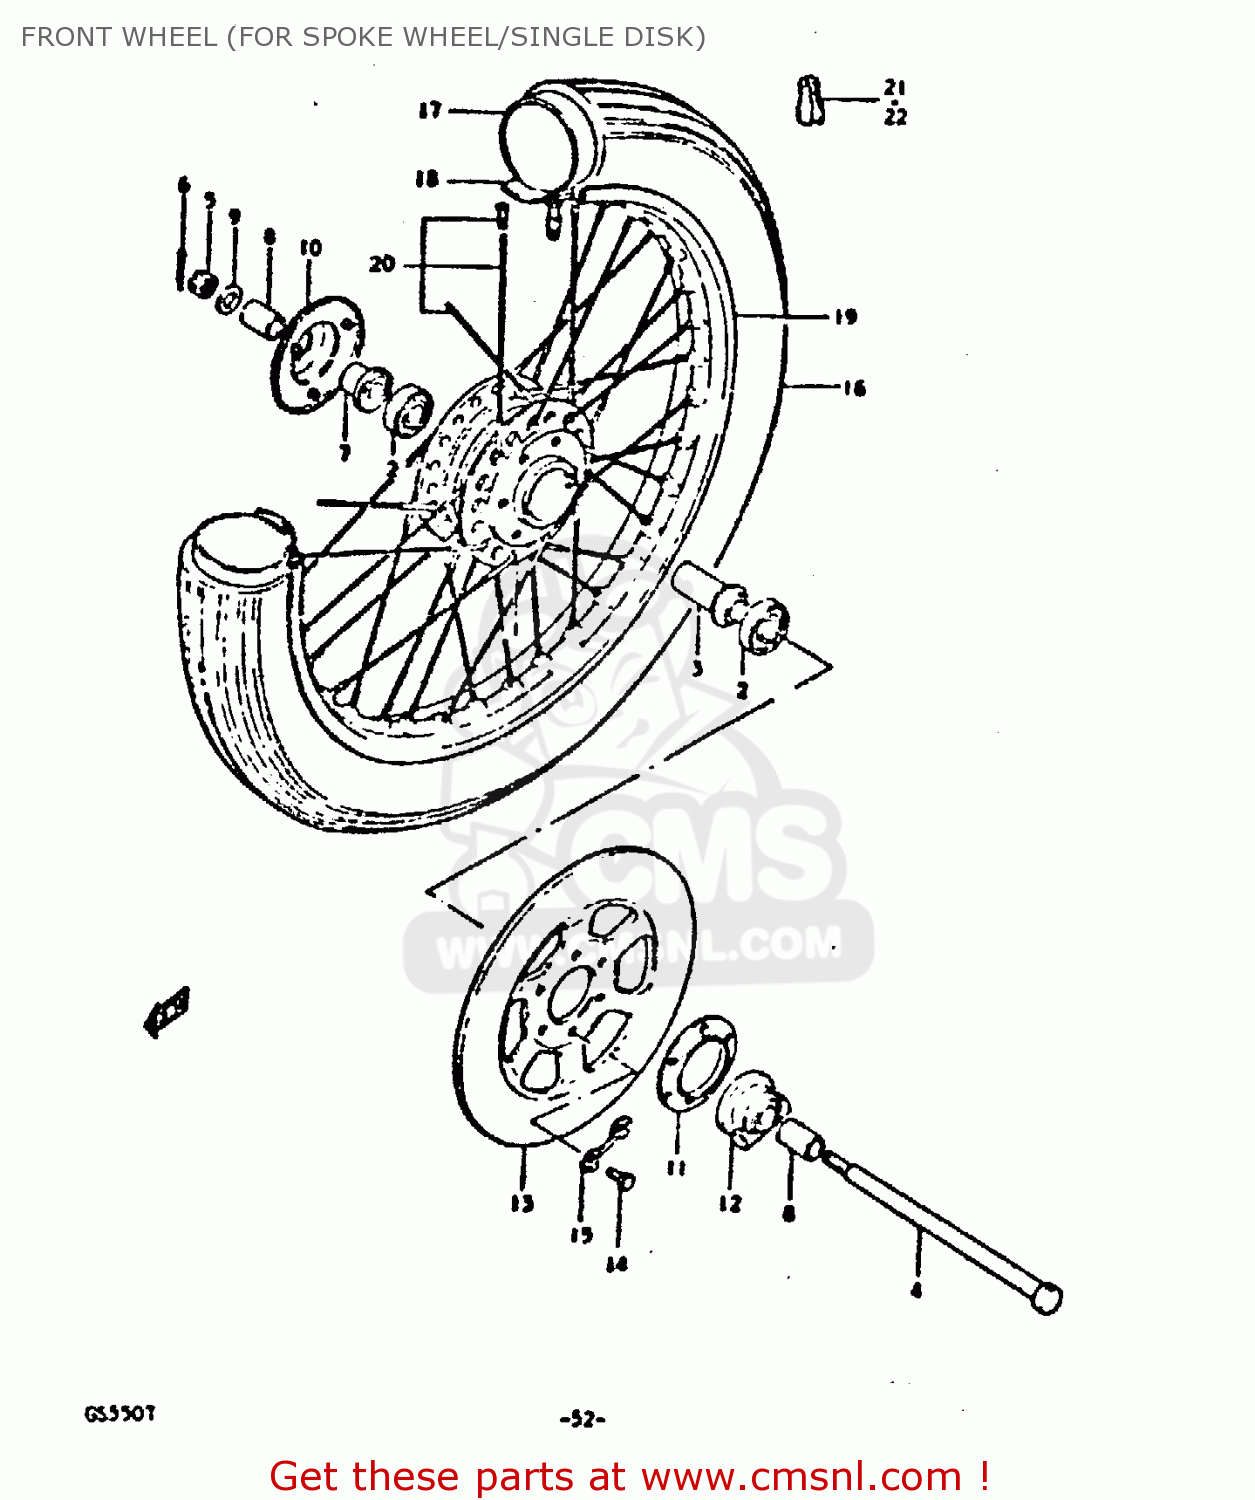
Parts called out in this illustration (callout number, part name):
1	DRUM,FRONT HUB
2	BEARING
3	SPACER,FR HUB BEARING
4	AXLE,FRONT
5	NUT 12MM
6	COTTER PIN
7	SPACER,FR AXLE,R
8	SPACER(15X22X30)
9	WASHER
10	COVER,FR HUB,R
11	DUST SEAL,SPEEDOMETER GEAR BOX
12	BOX ASSEMBLY,SPEEDOMETER GEAR
13	DISC,BRAKE
14	BOLT(8X25)
15	WASHER
16	TIRE (3.25H19)
17	TUBE,INNER
18	PROTECTOR,WHL INR TUBE
19	RIM,FR WHEEL
20	SPOKE SET,FRONT
21	BALANCER,WHEEL (B)
22	BALANCER,WHEEL (30G)
